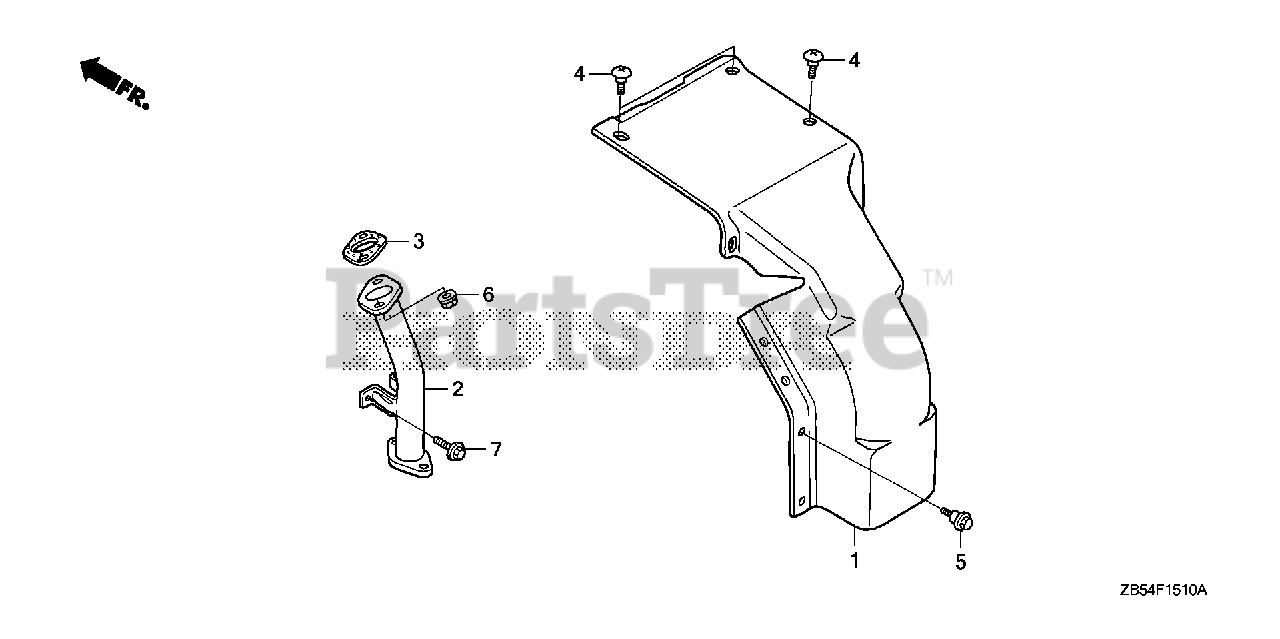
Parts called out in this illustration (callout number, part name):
1	COVER, EX. OUTLET
3	GASKET, MUFFLER
4	BOLT, FAIRING (6MM)
5	BOLT, FLANGE (6MM)
6	NUT, FLANGE (8MM)
7	BOLT, FLANGE (6X12) Use up to Engine SN 1543277.
